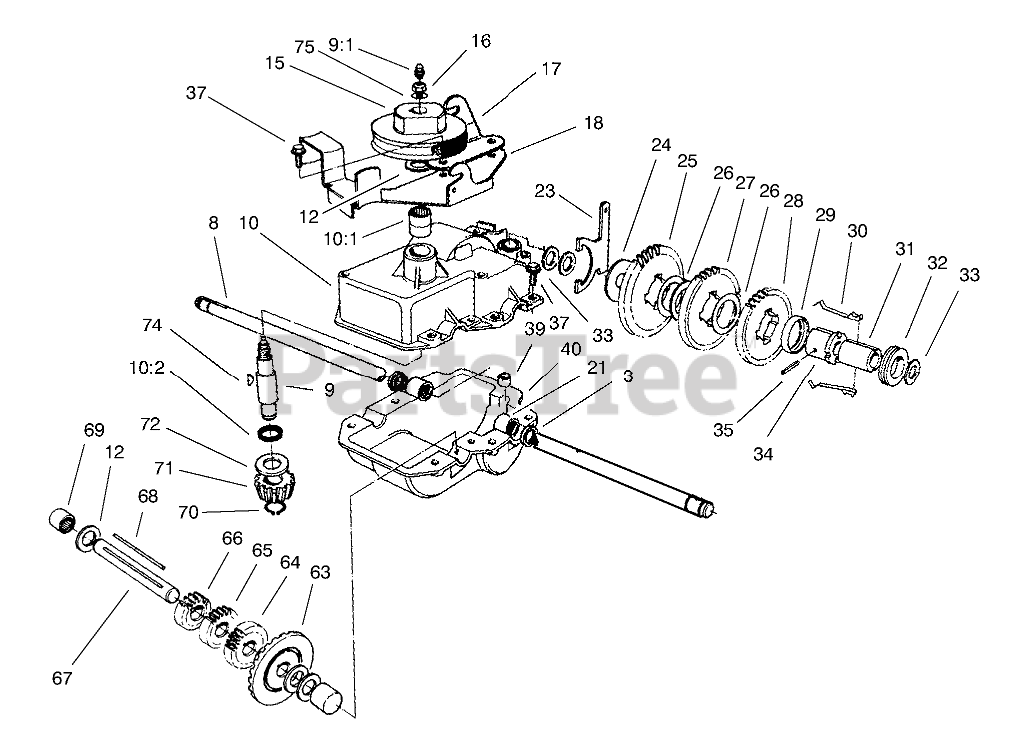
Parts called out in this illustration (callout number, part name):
3	BEARING-ROLLER
8	SHAFT-OUTPUT
9	INPUT SHAFT ASM
9:1	FITTING-GREASE, ZERK
10	UPPER GEARCASE ASM
10:1	BEARING-NEEDLE
12	WASHER-THRUST
15	PULLEY
16	NUT-HEX
17	Bracket-Traction Engage
18	Belt Guide Bracket
21	SEAL-OIL
23	YOKE-SHIFT
24	WASHER
26	WASHER
27	GEAR-42T
28	GEAR-38T
29	RETAINER-KEY
30	KEY-SHIFT
31	SLEEVE
32	COLLAR-SHIFT
33	WASHER-PLAIN
34	SLEEVE-GEAR
35	PIN-GROOVE
37	SCREW-HWHTF
39	BUSHING-YOKE
40	CASE-GEAR, LOWER
63	GEAR-BEVEL
64	GEAR-18T
65	GEAR-14T
66	GEAR-12T
67	SHAFT-INTERMEDIATE
69	BEARING-NEEDLE, CLOSED
71	PINION-BEVEL
72	WASHER-THRUST
74	KEY-WOODRUFF
75	WASHER-FLAT
